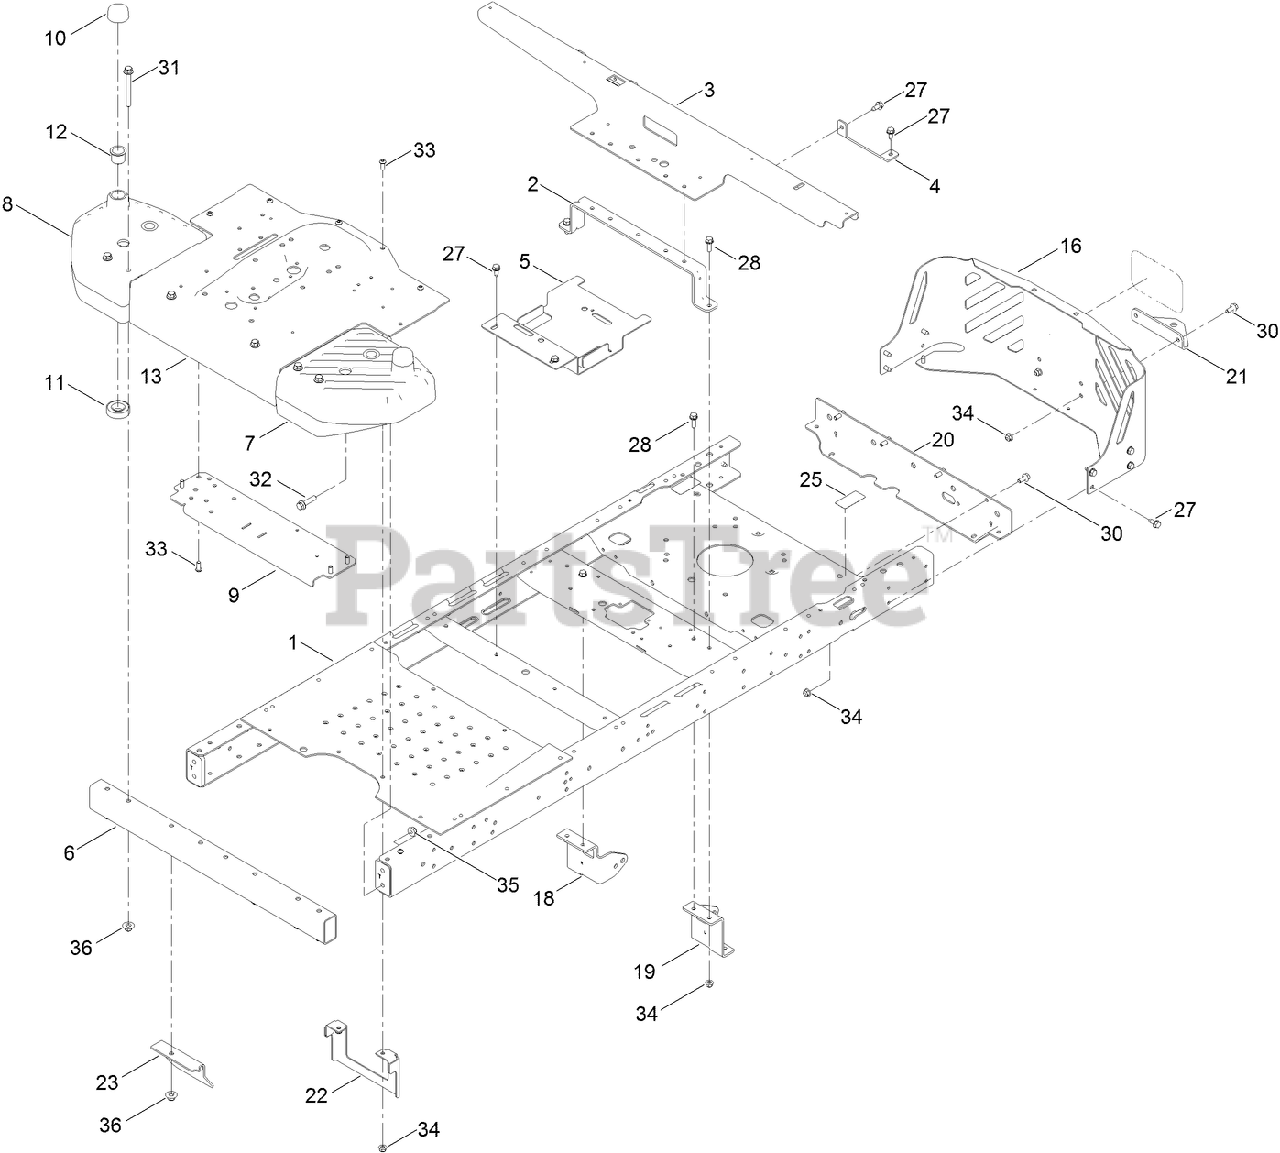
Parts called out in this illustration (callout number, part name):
1	FRAME ASM (WIDE)
2	BRACE-SEAT, REAR (WIDE)
3	SUPPORT-POD, WIDE
4	SUPPORT-TANK, REAR
5	BRACKET-BATTERY
6	TUBE-FRONT, WIDE
7	HOUSING-SPINDLE, LH
8	HOUSING-SPINDLE, RH
9	PLATE-BRIDGE, WIDE
10	CAP-CASTER
11	BEARING-BALL
12	BUSHING-PIVOT
13	PAN-STEER, FRONT
16	GUARD-ENGINE, WIDE
18	MOUNT-HYDRO, FRONT (RH)
19	MOUNT-HYDRO, FRONT (LH)
20	CROSSMEMBER-REAR, WIDE
21	BRACKET-HITCH
22	BRACKET-UPSTOP
23	GUARD-FRONT
25	DECAL-BYPASS
27	SCREW-HWHTF
28	SCREW-HHF
30	SCREW-HHF
31	SCREW-HHF
32	SCREW-HHF
33	SCREW-HSBH
34	NUT-HF, NI
35	NUT-HF, NI
36	NUT-FLANGE, NI
